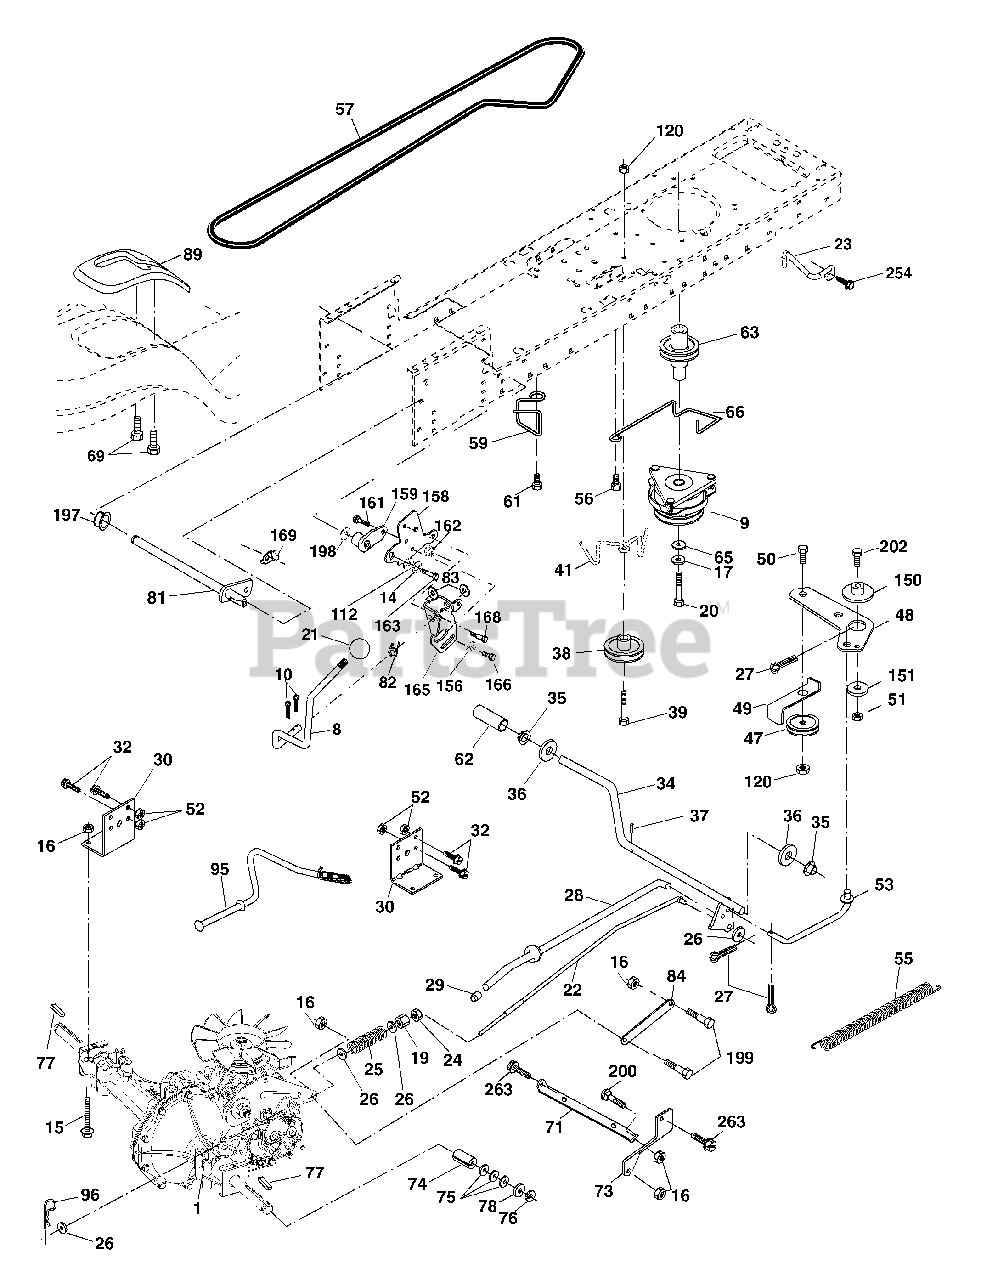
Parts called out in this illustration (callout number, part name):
8	Rod Shift Fender
9	Clutch Electric
10	Pin Cotter 1/8 x 1 CAD
14	Washer Lock Hvy Helical
15	Bolt Hex Flghd 5/16-18 Gr. 5
16	Nut Lock Hex W/Ins. 5/16-18 unc
17	Washer 1-1/2 OD x 15/32 ID x .250
19	Nut Lock Hex W/Wsh 3/8-16 unc
20	Bolt, Hex 7/16-20 x Gr. 5-1.5
22	Rod, Brake Hydro
23	Bracket Asm. Anti-Rot
24	Locknut
25	Spring, Brake Rod
26	Washer
27	Pin Cotter 1/8 x 3/4 CAD.
28	Rod, Parking Brake
29	Cap, Parking Brake
30	Bracket, Transaxle
32	Bolt Hex Hd 5/16-18 unc x 3/4
34	Shaft, Foot Pedal Nibbed
35	Bearing, Nylon
36	Washer
37	Pin, Roll
38	Pulley, Idler, Flat Composite
39	Bolt 3/8-16 x 2-3/4 Gr. 5
41	Keeper, Belt Idler Fool-Proof
47	Pulley, Idler, V-Groove
48	Bellcrank Clutch Grnd Drv Stl
49	Retainer, Belt
50	Bolt Carr. SH 3/8-16 x 1-1/2 Gr. 5
52	Nut Crown Lock 5/16-18
53	Link, Clutch
55	Spring, Return, Clutch
56	Screw 3/8-16 x 1-1/4
57	V-Belt, Ground Drive
59	Keeper, Center Span
61	Screw 3/8-16 x .875
62	Cover, Pedal
63	Pulley, Engine
65	Washer
66	Keeper Belt Engine Hydro
69	Screw Hex Wsh Hi-Lo 1/4-1/2
71	Strap Torque Lh Hydro
73	Strap Torque Rh Hydro
74	Spacer, Axle
75	Washer 25/32 x 1-1/4 x 16 Ga.
77	Key, Square
78	Washer 25/32 x 1-5/8 x 16 Ga.
81	Shaft Asm. Cross Hydro
82	Spring Torsion T/A
83	Washer 17/32 x 3/4 x 16 Ga.
84	Link Transaxle
89	Console, Shift
95	Control Asm. Bypass Hydro
96	Retainer Spring 1" Zinc/Cad
112	Washer 9/32 x 3/4 x 10 Ga.
120	Nut Lock 3/8-16
150	Spacer Retainer
151	Washer 13/32 x 2 x 10 Ga.
156	Washer Srrted 5/16 ID x 1.125
158	Bracket Shift Mount
159	Hub Shift
161	Bolt Rdhd Sqnk 1/4-20 x 3/4 Gr. 5
162	Nut Crownlock 1/4-20 unc
163	Bolt Hex Fin 1/4-20 unc x 1 Gr. 5
165	Bracket Pivot Lever
166	Screw 5/16-18 x 5/8
168	Bolt Shoulder 5/16-18 x .561
169	Plate Fastening Lt\
197	Nyliner Snap-In 5/8" ID
198	Washer Nyliner 7/8 ID x .105
199	Bolt Shoulder 5/16-18 unc
200	Bolt Rdhd Sq Neck 5/16-18 unc x 1
202	Bolt 3/8-16 x 1-3/4 Gr. 5
254	Screw 3/8-16 x 1
263	Screw Hexwsh Thdr 3/8-16 x 3/4
